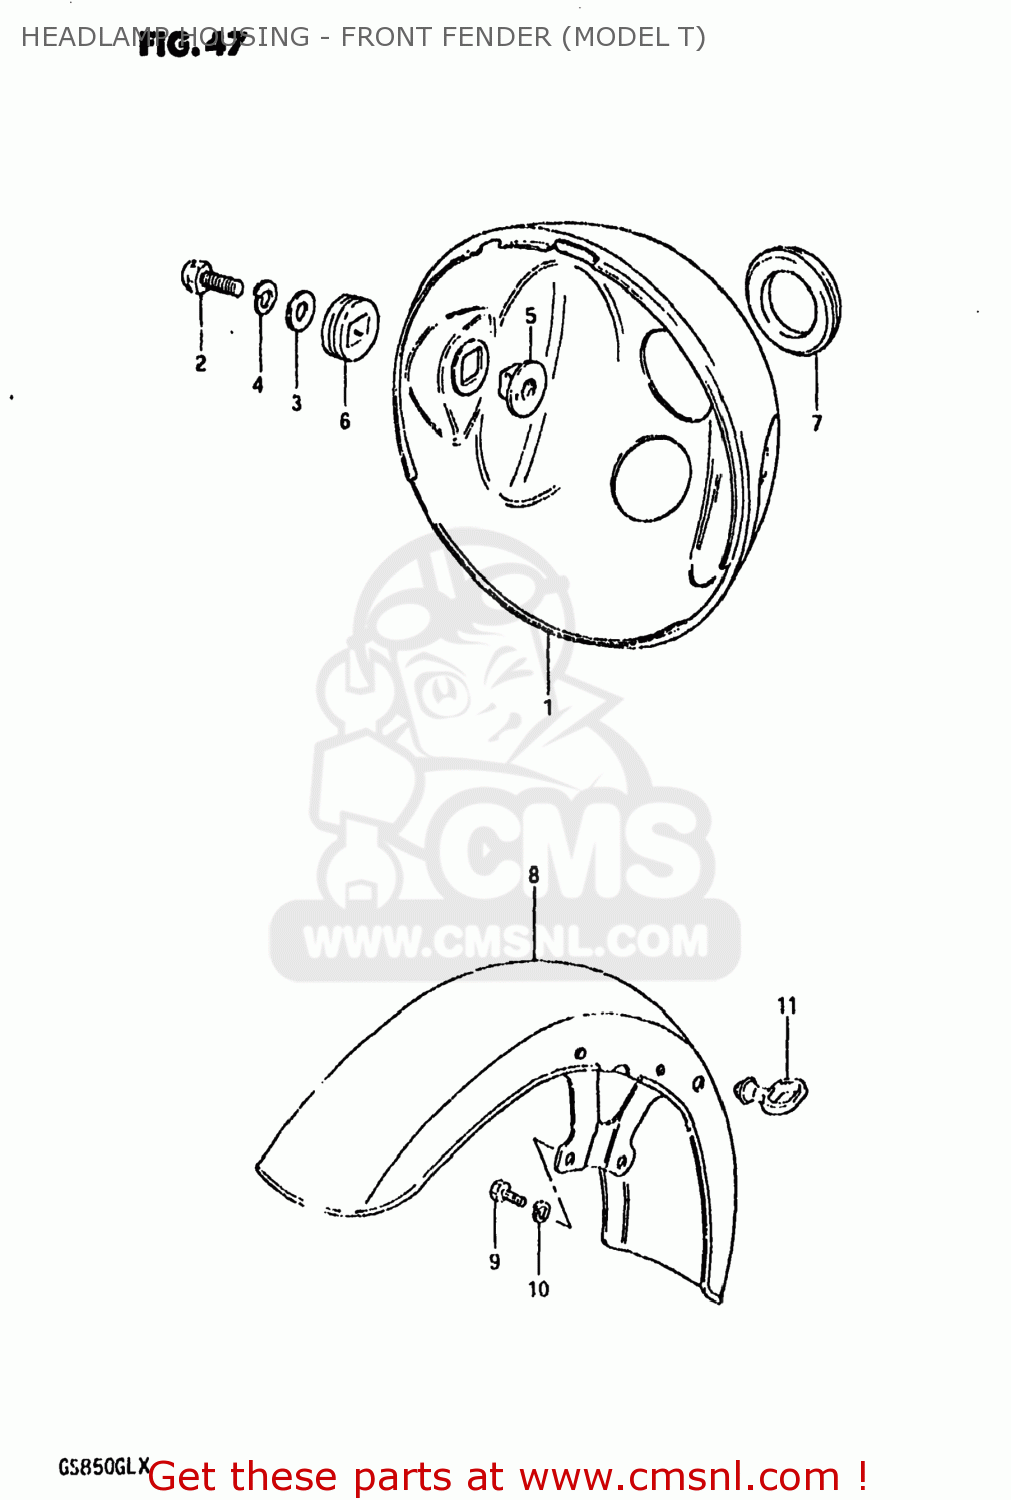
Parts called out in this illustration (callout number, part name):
1	HOUSING,HEADLAMP
2	BOLT
3	WASHER
4	LOCK WASHER
5	SPACER,HEADLAMP HOUSING
6	CUSHION,HEADLAMP HOUSING
7	GROMMET,HEADLAMP HOUSING
8	FENDER,FRONT
9	BOLT
10	LOCK WASHER
11	GUIDE,CABLE
